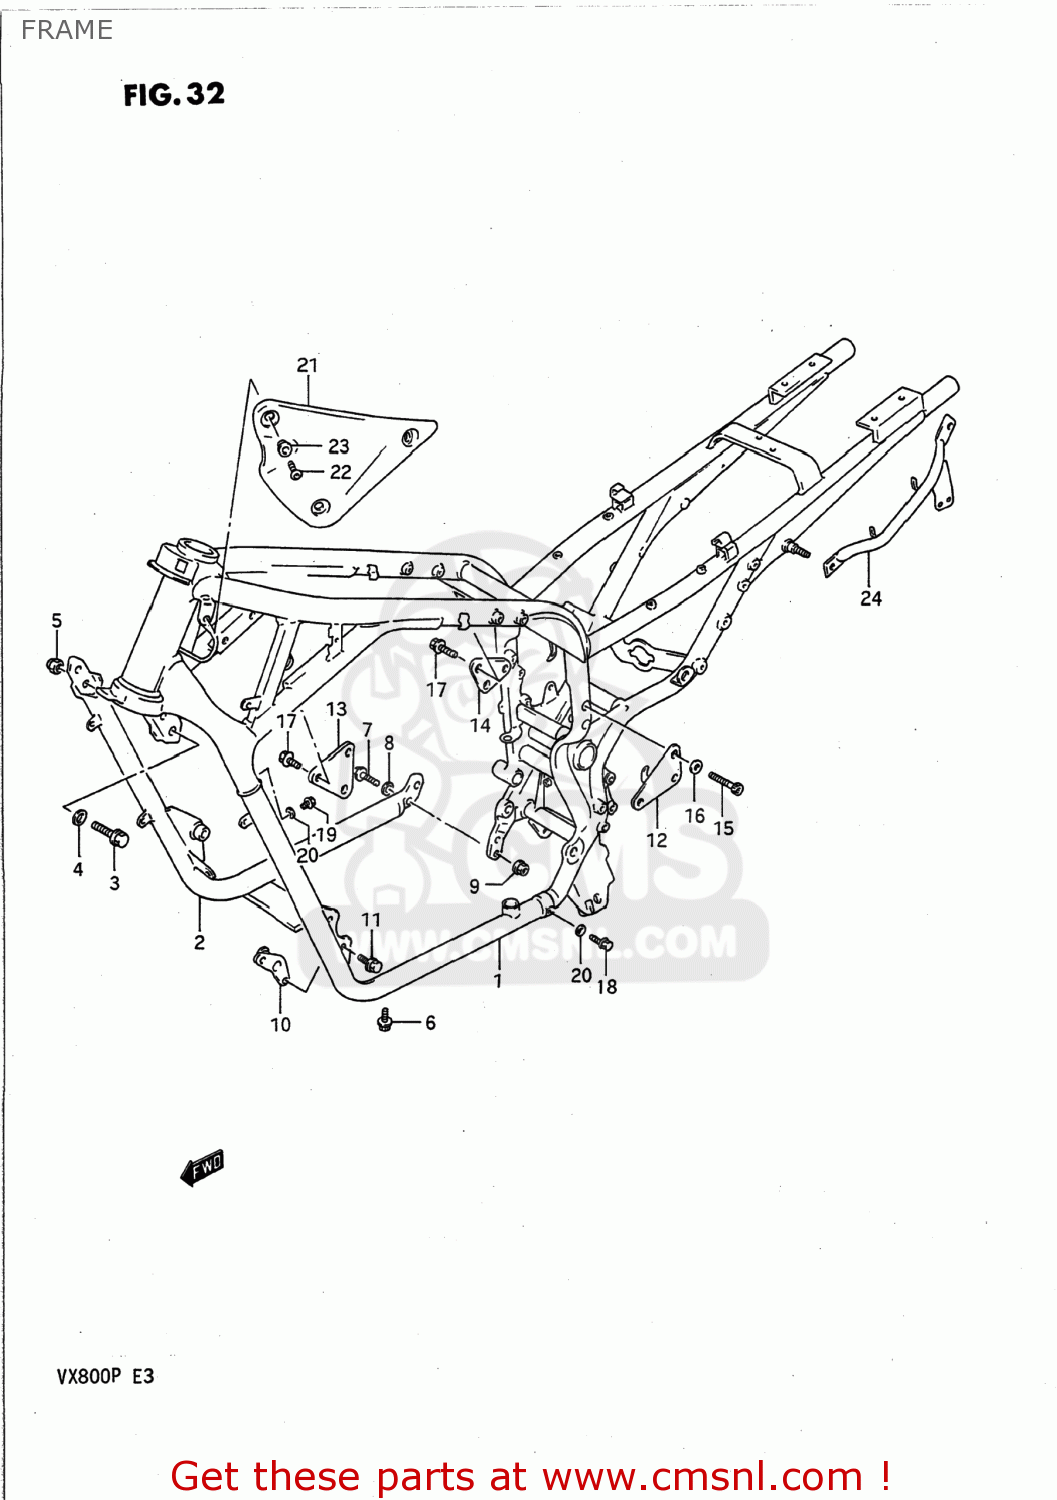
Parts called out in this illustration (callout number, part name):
1	FRAME
2	TUBE COMP,FRAME DOWN,LEFT
3	BOLT(10X32)
4	WASHER
5	NUT
6	BOLT
7	BOLT(10X33)
8	WASHER
9	NUT 10MM
10	PLATE,ENGINE MOUNTING
11	BOLT
12	PLATE,ENGINE MOUNTING NO
13	PLATE,ENGINE MOUNTING
14	PLATE,ENGINE MOUNTING NO
15	BOLT
16	WASHER
17	BOLT
18	BOLT
19	UNION
20	GASKET(6.2X11X1).2 (NAS)
21	COVER,FRAME HEAD,LEFT
22	SCREW(5X14)
23	WASHER(5.2X14X1.5)
24	GRIP COMP,REAR,LEFT
